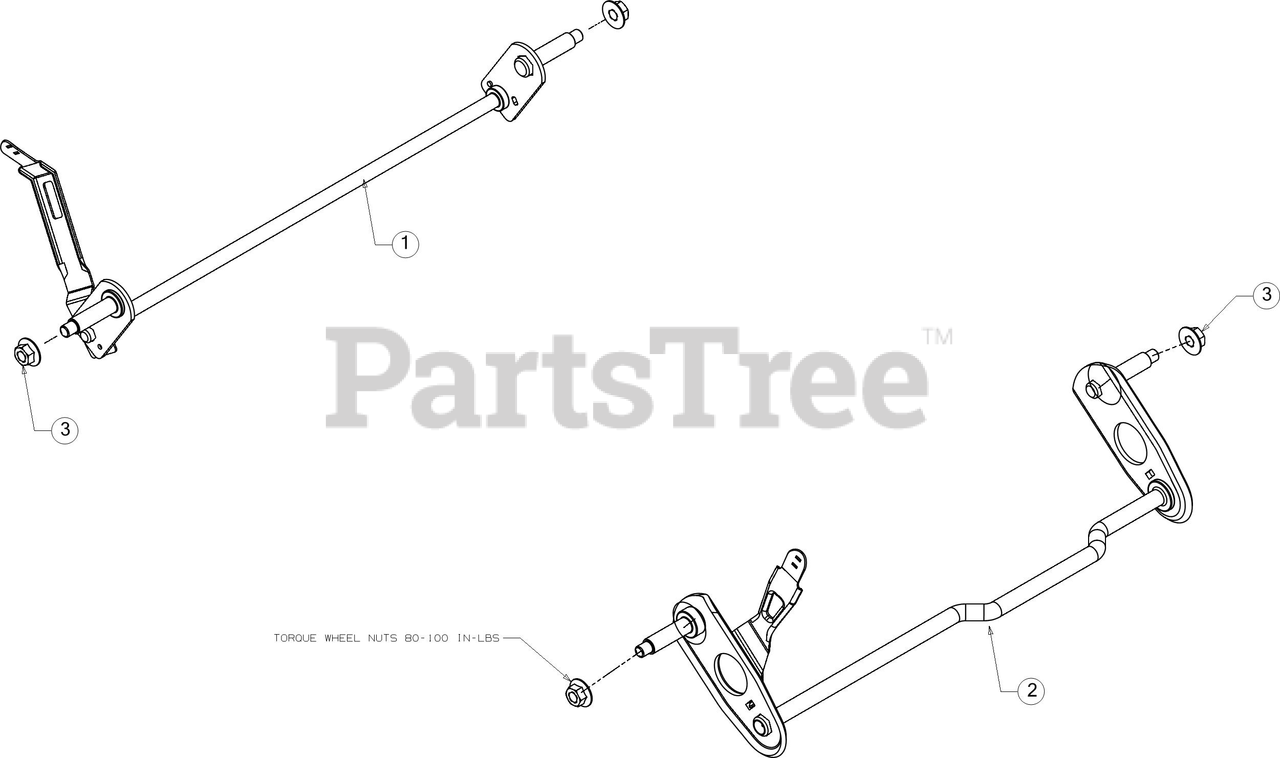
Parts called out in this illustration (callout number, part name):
1	8" REAR AXLE ASSEMBLY
2	8" FRONT AXLE ASSEMBLY
3	FLANGE LOCK NUT
